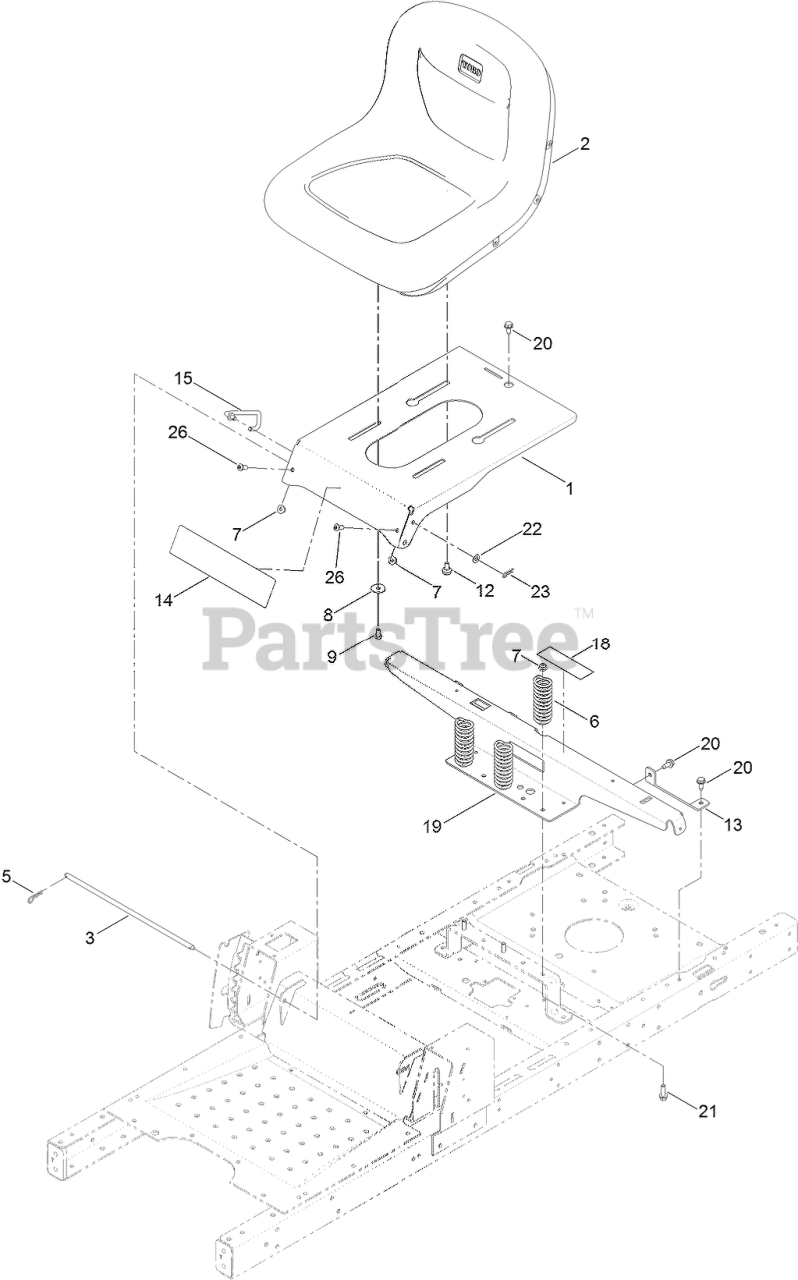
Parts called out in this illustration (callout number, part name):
1	PAN-SEAT
2	SEAT-15 INCH
3	ROD-PIVOT, NARROW
5	PIN-COTTER
6	SPRING-COMPRESSION
7	NUT-HF, NI
8	WASHER-PIVOT
9	SCREW-HH
12	BOLT-SHOULDER
13	SUPPORT-TANK, REAR
14	DECAL-TIMECUTTER
15	STOP-SEAT
18	DECAL-SERVICE, CE
19	SUPPORT-POD
20	SCREW-HWHTF
21	SCREW-HHF
22	WASHER-PLAIN
23	PIN-COTTER
26	SCREW-HSBH
